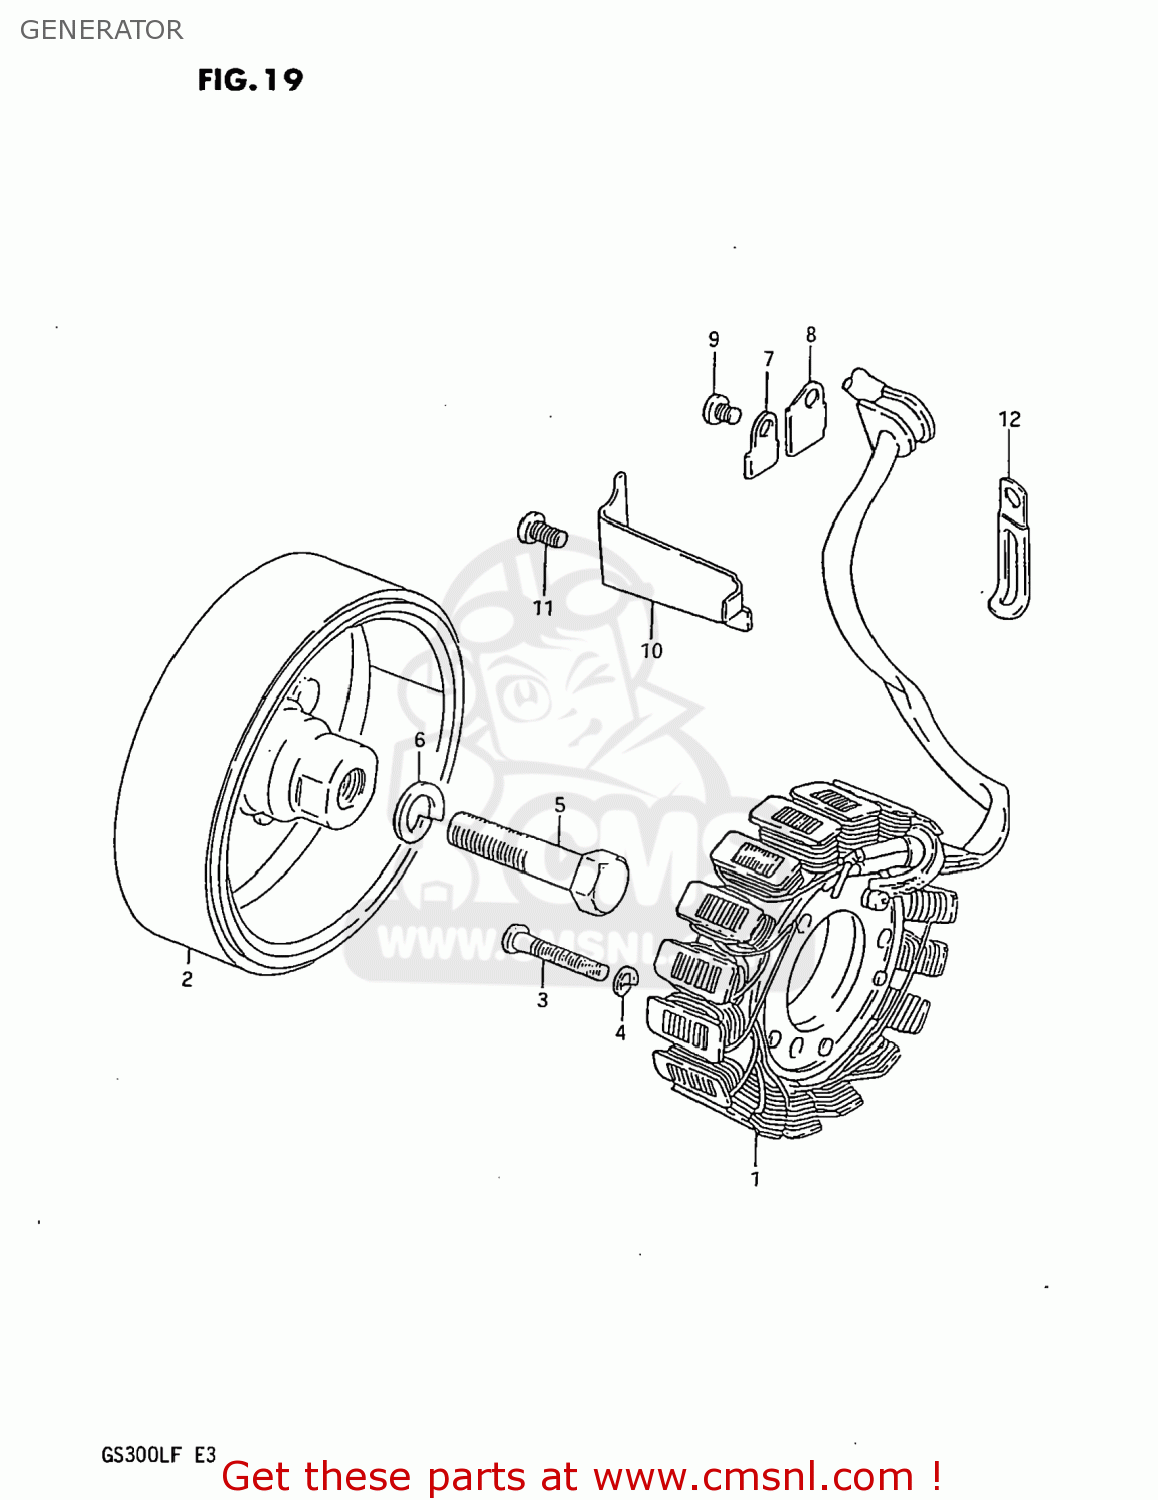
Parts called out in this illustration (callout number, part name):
1	STARTER ASSY
2	ROTOR ASSY
3	SCREW
4	LOCK WASHER
5	BOLT 12X45
6	WASHER,LOCK 12
7	CLAMP,GENERATOR LEAD WIRE
8	CLAMP,GENERATOR LEAD WIRE
9	SCREW
10	CLAMP,GENERATOR LEAD WIRE
11	SCREW
12	CLAMP L:35
